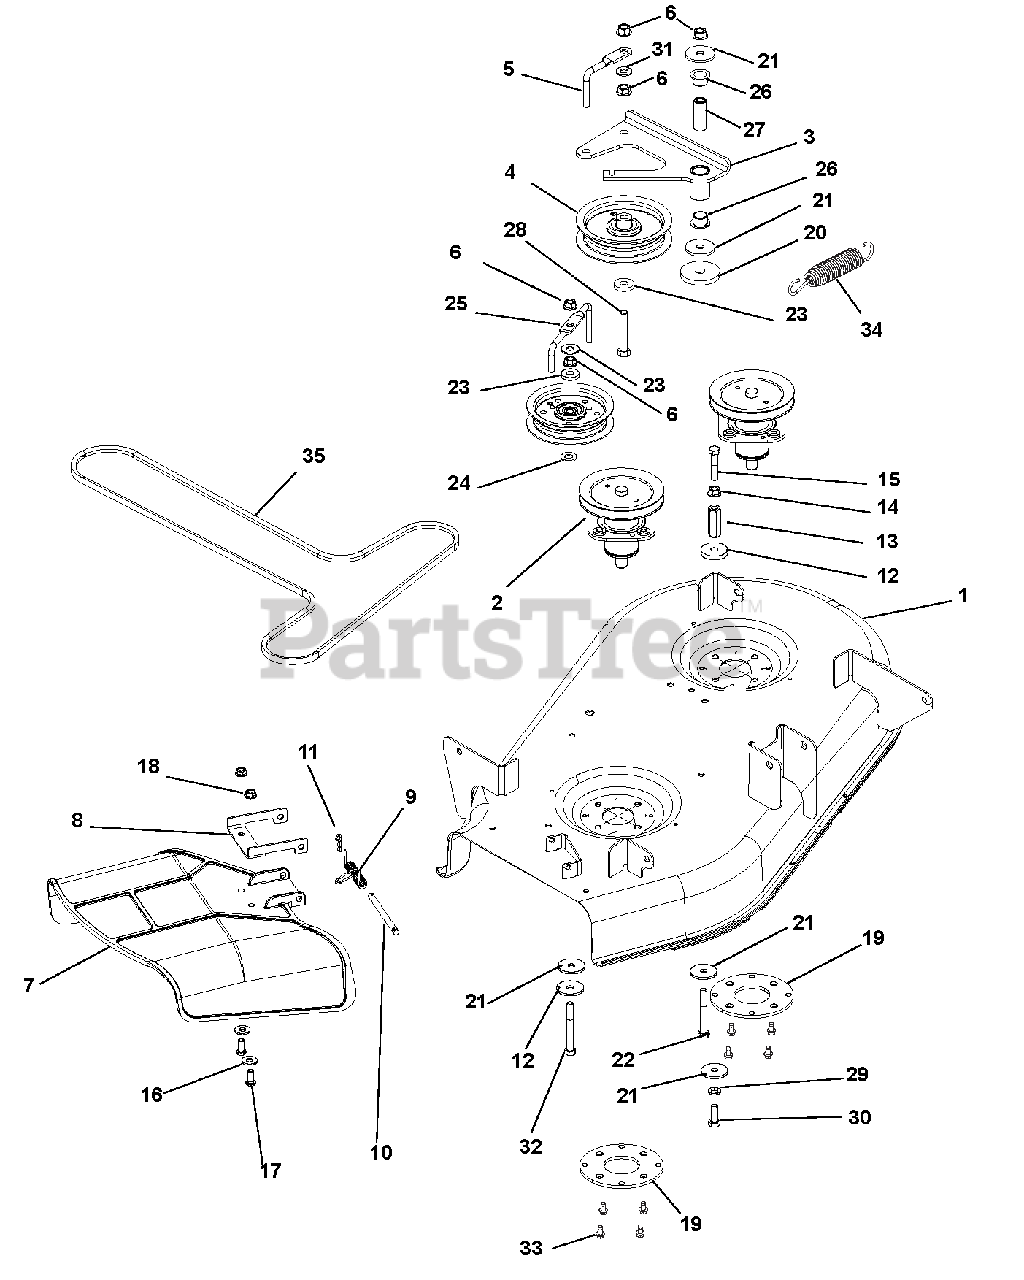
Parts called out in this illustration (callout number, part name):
1	KIT, 34" ARIENS DECK W/DECALS
1	KIT, 34" ARIENS CE DECK&DECALS
2	KIT, DECK SPINDLE ASM (34/50)
3	IDLER ARM
4	ASM, IDLER 4"
5	WIREFORM, BELT FINGER
6	@NUT-LK-TOP-FLG .38-16 YWZC
7	CHUTE, SIDE DISCHARGE
8	CHUTE REINFORCEMENT
9	SPRING, TORSION
10	PIN, 5/16 X 3.88"
11	PIN-HAIR INT .08X.18X1.18 YWZC
12	WSHR,FLT STL.406X1.50X.245YWZC
13	NUT COUPLING .375-16X1.75
14	@NUT-SPNLK-FLG .375-16 YWZC
15	@BLT-HEX .38-16X1.75 GR5 YWZC
16	@WSHR-FL-STL.38X.875X.083 YWZC
17	SCR-SKH .31-18X.75 BTNHD YWZC
18	@NUT-LK-TOP-FLG .31-18 YWZC
19	PLATE-REINF, SPINDLE
20	WSHR-FL-STL .469X2.00X.25 YWZC
21	WSHR-FL-STL .380X1.50X.125YWZC
22	@BLT-HEX .38-16X3.00 GR5 YWZC
23	WSHR-FL-STL .406X1.00X.188 YWZ
24	@WSHR-FL-STL.438X1.00X.083 YWZ
25	WIREFORM, BELT FINGER
26	BSHG-FLG, .625X.750X.500X1.00
27	SPACER, .375IDX.625ODX1.66 PM
28	@BLT-HEX .38-16X2.25 GR5 YWZC
29	@WSHR-LK .38X.094 REG YWZC
30	@BLT-HEX .38-16X1.00 GR5 YWZC
31	@WSHR-FL-STL.406X.812X.065 YWZ
32	@BLT-HEX .38-16X2.75 GR5 YWZC
33	@SCR-TAP .38-16X.75 HWH TR YWZ
34	SG-TENS .135X.98X6.0 WLD 62
35	V-BELT, HA-WRAPPED
